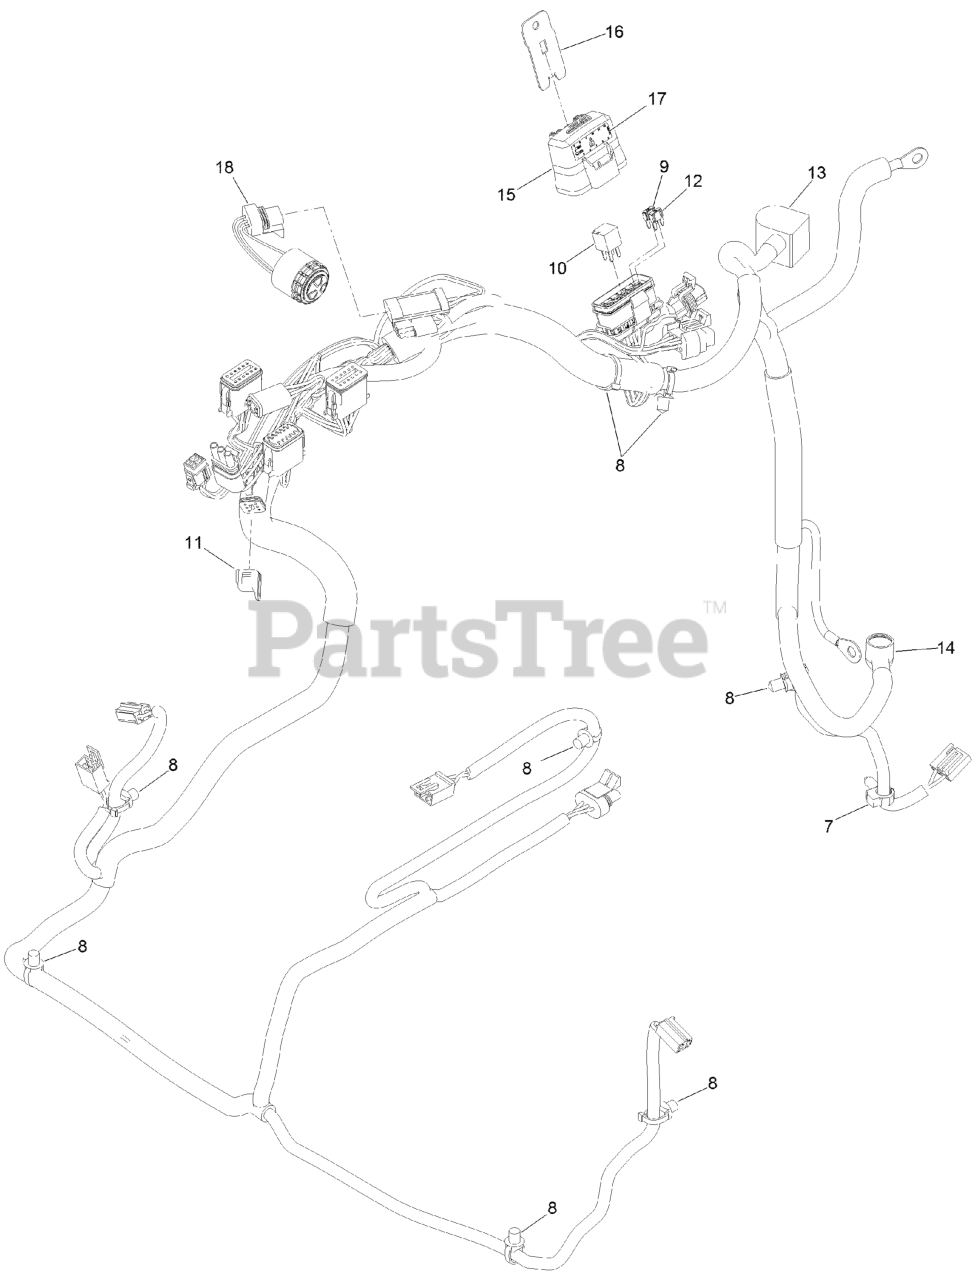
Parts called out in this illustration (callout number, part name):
7	CLIP-HARNESS
8	CLIP-TIE
9	FUSE-MINI BLADE, 20 AMP
10	RELAY-MICRO
11	CAP-PLUG, 6 WAY
12	FUSE-MINI BLADE, 15 AMP
13	INSULATOR-BATTERY
14	INSULATOR-SOLENOID
15	COVER-BLOCK, FUSE
16	CLIP-MOUNTING
17	DECAL-FUSE
18	ALARM-DUAL TONE
